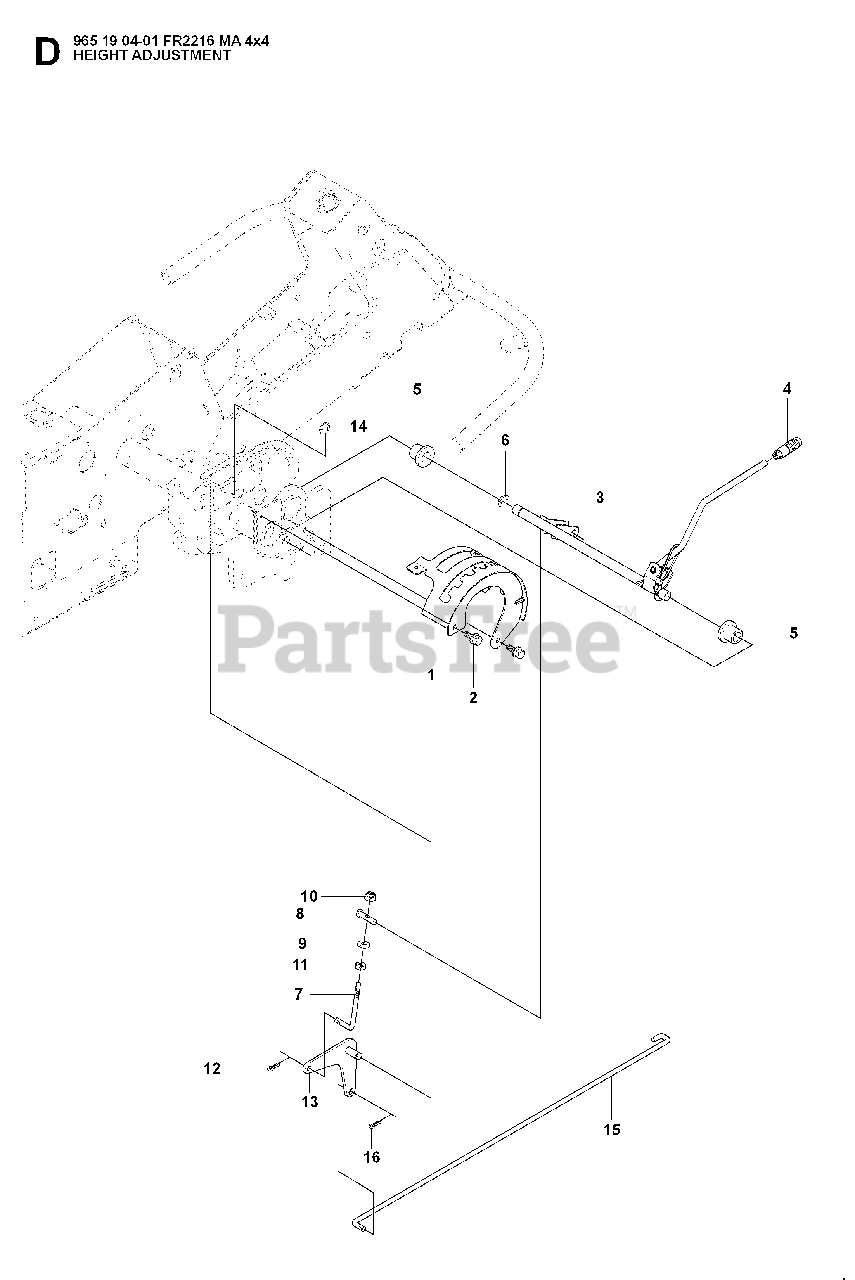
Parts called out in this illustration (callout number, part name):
4	GEAR STICK KNOB
5	BUSHING
9	WASHER
10	LOCKNUT M8
11	NUT
12	SPLIT PIN
14	RETAINING RING
16	SPLIT PIN
